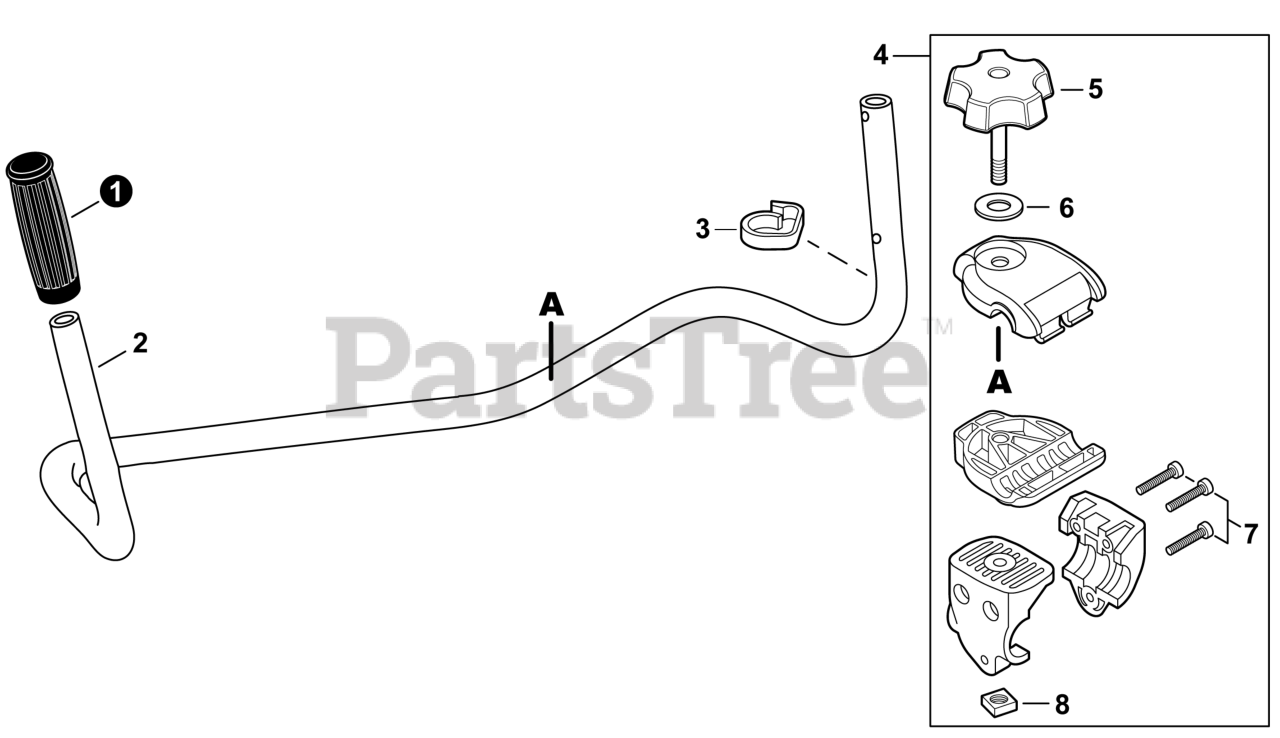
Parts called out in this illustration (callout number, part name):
1	GRIP, HANDLE
2	HANDLEBAR
3	CLIP, CABLE
4	BRACKET KIT, HANDLEBAR
5	KNOB, SCREW M8
6	WASHER 8
7	BOLT, TORX 5x25
8	NUT 8x1.25
